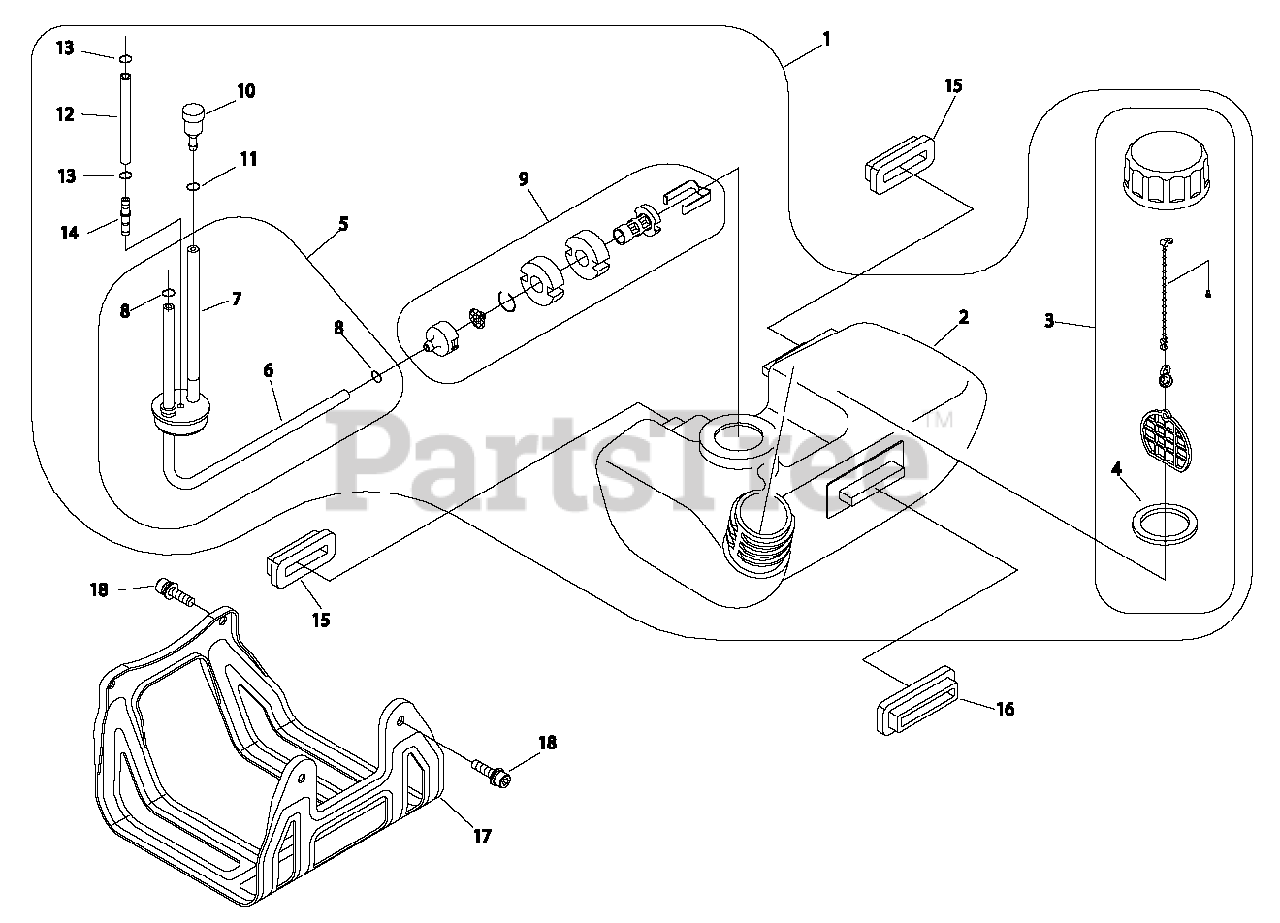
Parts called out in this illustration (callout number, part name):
1	FUEL TANK ASSY
2	TANK, FUEL
3	CAP ASSY - RED
4	GASKET, CAP
5	FUEL PIPE ASSY
6	PIPE - FUEL
7	PIPE - VENT
8	CLIP - 6
9	FUEL FILTER ASSY
10	VENT, FUEL TANK
11	CLIP - 6
12	PIPE - RETURN
13	CLIP - 6
14	CONNECTOR, PIPE
15	CUSHION, FUEL TANK
16	CUSHION, FUEL TANK
17	GUARD, FUEL TANK
18	SCREW - 5X16
